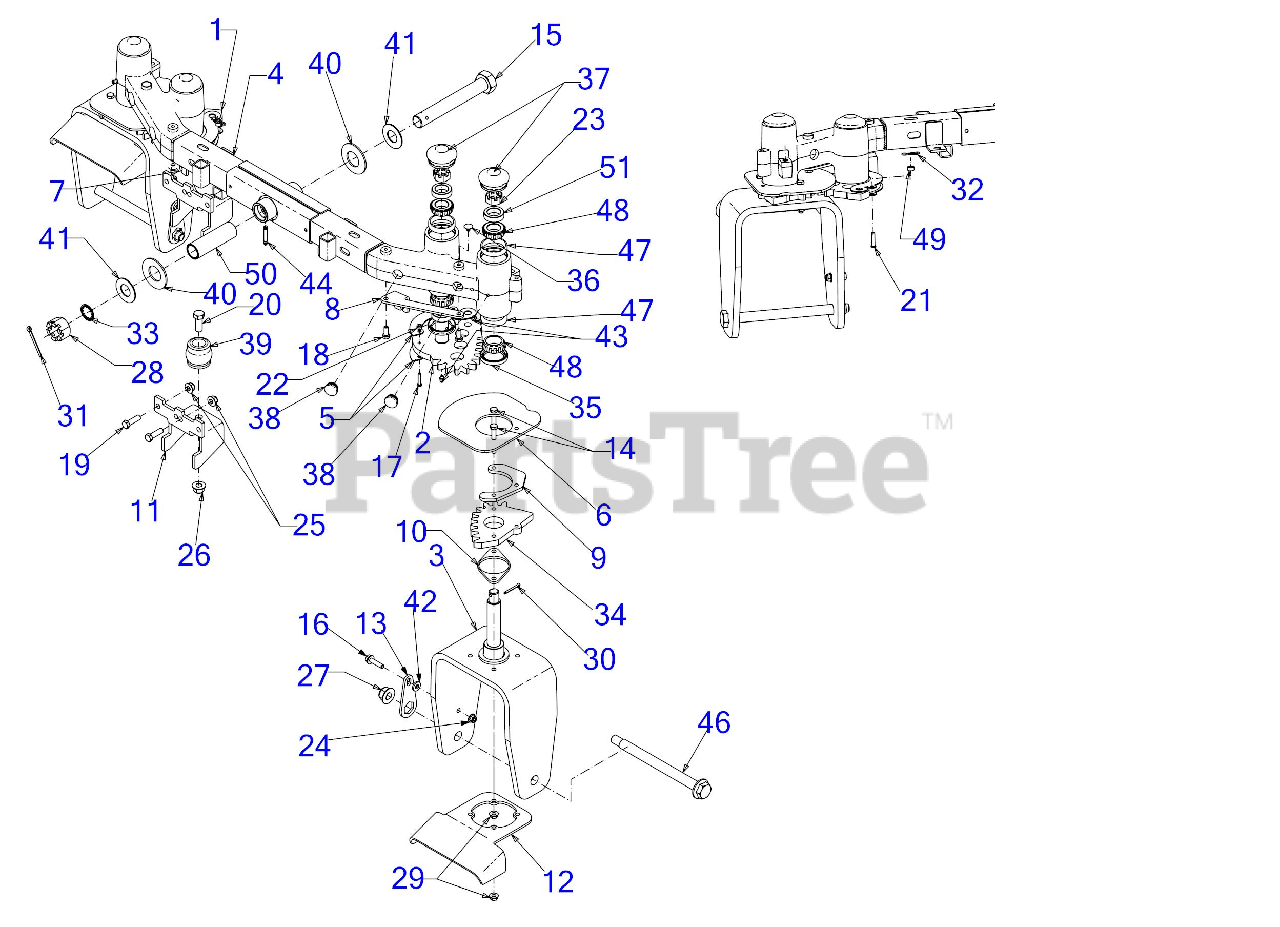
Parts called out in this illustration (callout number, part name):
1	STEERING GEAR (LH)
2	STEERING GEAR (RH)
10	LOWER GEAR SPACER PLATE
14	HEX SCREW 5/16-18 x 2.25 GR5
15	HEX HEAD SCREW 1-14 X 7 GR5
16	SCREW 5/16-18 x 1.25 GR5
17	SCREW #10-24 x 1.00 GR5.1
18	SCREW 5/16-18 x .750
19	SCREW 3/8-16 x 1.25 GR5
20	SCREW 1/2-13 x 1.25 GR5
21	CLEVIS PIN .25 x 1.00
23	HEX NUT CASTLE 3/4-16
24	FLANGE LOCK NUT 5/16-18
27	FLANGE LOCK NUT
28	CASTLE NUT 1.0-14 GR5
29	HEX FLANGE NUT
30	COTTER PIN-5/32 DIA
31	COTTER PIN
32	BOW TIE COTTER PIN 1/4-5/16
33	RETAINING RING
34	STEERING GEAR YOKE
36	RATCHET CLIP
37	AXLE GREASE CAP
39	AXIAL BUMPER
40	BELL WASHER 1.25ID x 2.5 x .180
41	FLAT WASHER 1.0 x 2.0 x .075
42	FLAT WASHER
43	GREASE ZERT 1/4-28
44	GREASE FITTING
46	SHOULDER BOLT .750 X 8.175:5/8-11
47	BEARING CUP
48	BEARING CONE
